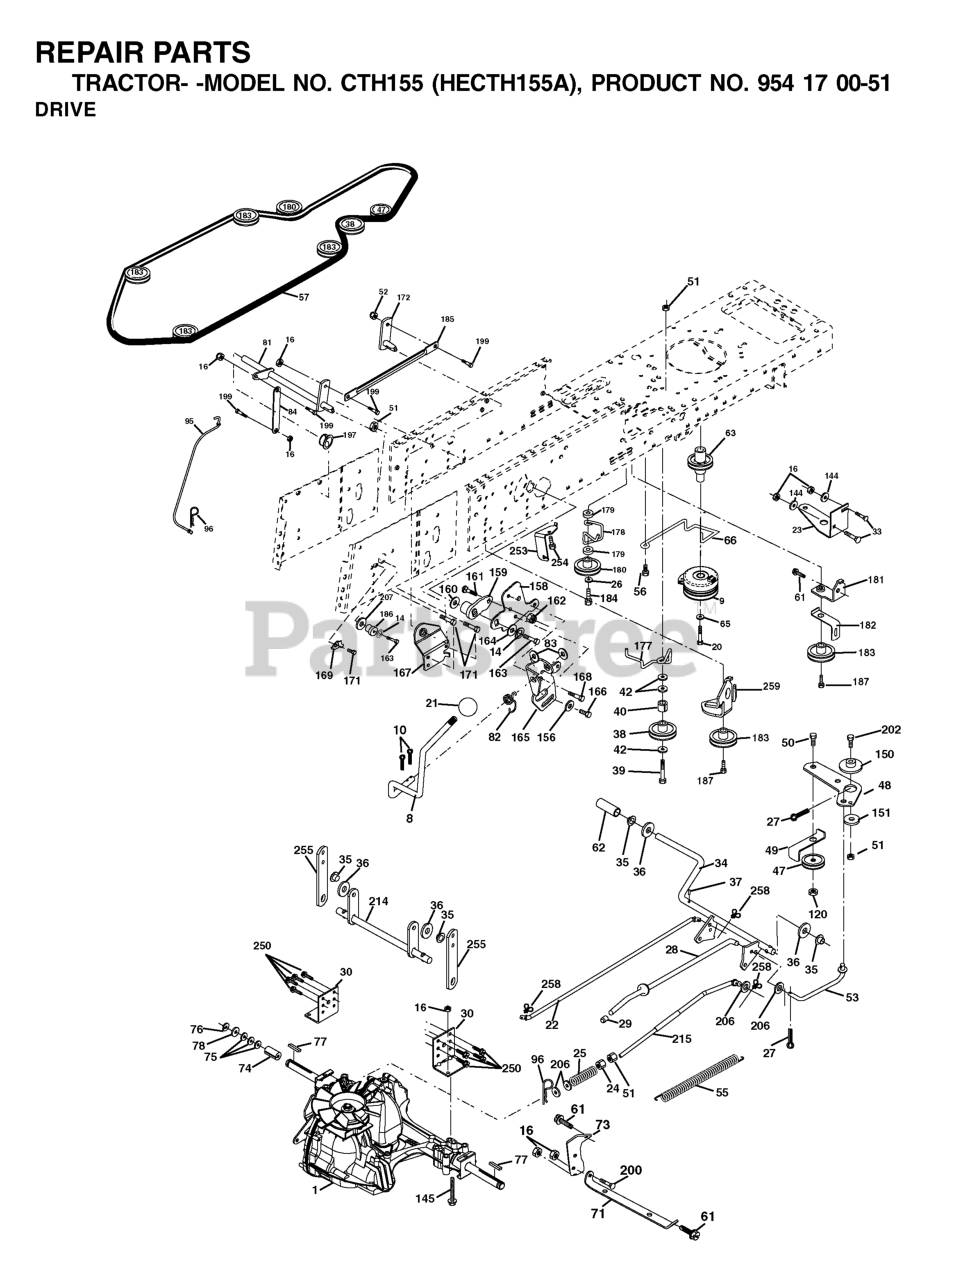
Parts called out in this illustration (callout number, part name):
8	ROD.SHIFT.FENDER.ADJ.LT.CRD
9	CLUTCH
10	PIN COTTER
14	LOCKWASHER
16	NUT.71038.31-18.HEX.NYLOCK
20	BOLT HEX
21	KNOB.DUCKHEAD.1/2
22	ROD
24	NUT
25	SPRING ROD LT
26	WASHER
27	COTTER PIN
28	ROD, PARKING BRAKE
29	PLUNGER CAP
30	BRKT, TRNSXLE MNT 20"
33	RP BOLT 5/16-18 X3/4 ZN/YEL GR
34	SHAFT, FOOT PEDAL
35	BEARING.NYLON
37	DRIVE PIN
38	PULLEY.FLAT
42	WASHER
47	IDLER PULLEY
48	BELLCRANK, CLUTCH
49	RETAIN BELT
50	BOLT
52	LOCKNUT
53	LINK, CLUTCH LT
55	SPRING, RETURN LT
56	SCREW.3/8-16
57	V-BELT 113"
61	SCREW 3/8-16X3/4
62	COVER, PEDAL (1 2)
63	PULLEY, CLUTCH ELECT EVX
65	LOCKWASHER
66	KEEPER BELT ENGINE
71	STRAP TORQUE LH HYDRO
73	STRAP TORQUE RH HYDRO
74	SPACER AXLE
77	SQUARE KEY
81	ASM.CROSS.SHAFT.REAR.CRD.0510
82	SPRING,TORSION
83	WASHER
84	LINK.PNT.TRANSAXLE.0510.CRD
95	LINK
96	RETAINER M
120	NUT LOCK FLG 3/8-16 UNC
144	Washer 11/32 x 5/8 x 16 Ga SD
145	BOLT HEX 5/16-18 GR 5
150	BUSHING.BELLCRANK.GRD.DR
151	WASHER 12/32X2X10GA
156	WASHER.SRRTD.5/16
158	BRACKET
159	HUB
160	Washer 29/32 x 1 - 1/4 x 16 Ga.
161	BOLT
162	NUT.CROWNLOCK.1/4
164	Washer 5/8 x .281 x 10 Ga.
165	RP BRACKET
167	BRACKET.SUPT.SHIFT.CRD
168	BOLT.SHOULDER.5/16-18X
169	PLATE.FASTENING.CROSS.SHAFT
172	LINK
174	LOCKWASHER
180	PULLEY.FLAT.IDLER
181	BRACKET
182	KEEPER BELT
184	SCREW.HXWSH.3/8
185	LINK
186	HUB.TAPERED.ROUND.CRD
187	BOLT.5/16-18X1.25
197	NYLINER SNAP 5/8" ID
199	BOLT SHOULDER 5/16-18 UNC
202	BOLT.3/8-16X1.50
206	WASHER
207	WASHER NYL
214	LEVER
215	ROD
250	SCREW 3/8-16X3/4
254	SCREW THDROL 3/8-16 X 1-1/2
255	SHAFT
258	CLIP RETAINER
